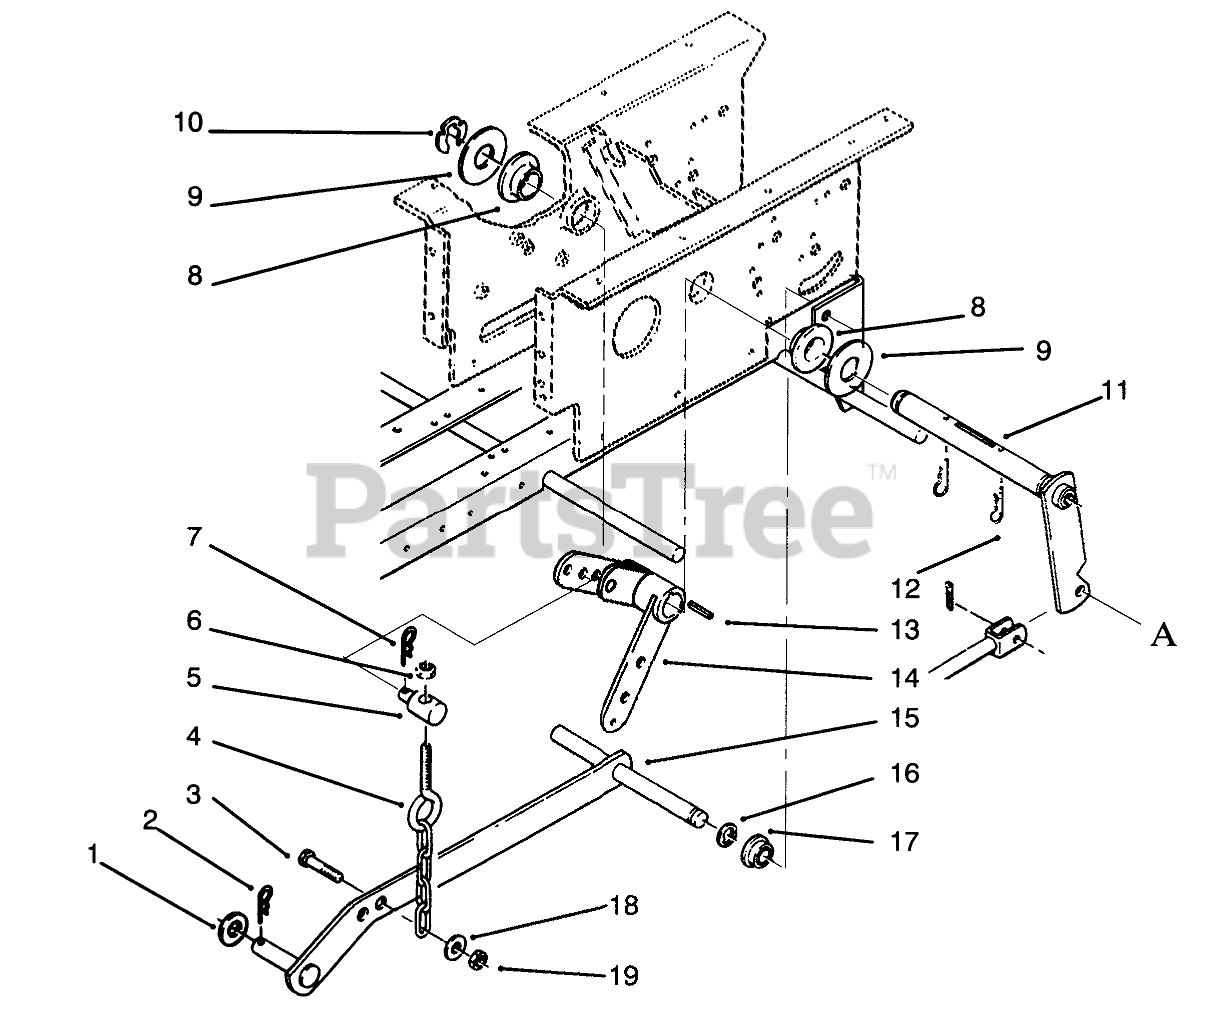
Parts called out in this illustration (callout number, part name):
1	WASHER-FLAT
2	PIN-HAIR
3	SCREW-HH
4	CHAIN-LIFT
5	TRUNNION-LIFT
6	NUT-LOCK, NI
7	PIN-HAIR
8	BEARING-FLANGE
9	WASHER-FLAT
10	RING-RETAINING
11	WLDMT-LIFT ARM
12	PIN-HAIR
13	KEY-SQUARE
14	LIFT LEVER ASM
15	Bar-Lift
16	RING-RETAINING, EXTERNAL
17	BUSHING
18	WASHER-PLAIN
19	NUT-LOCK, NI
